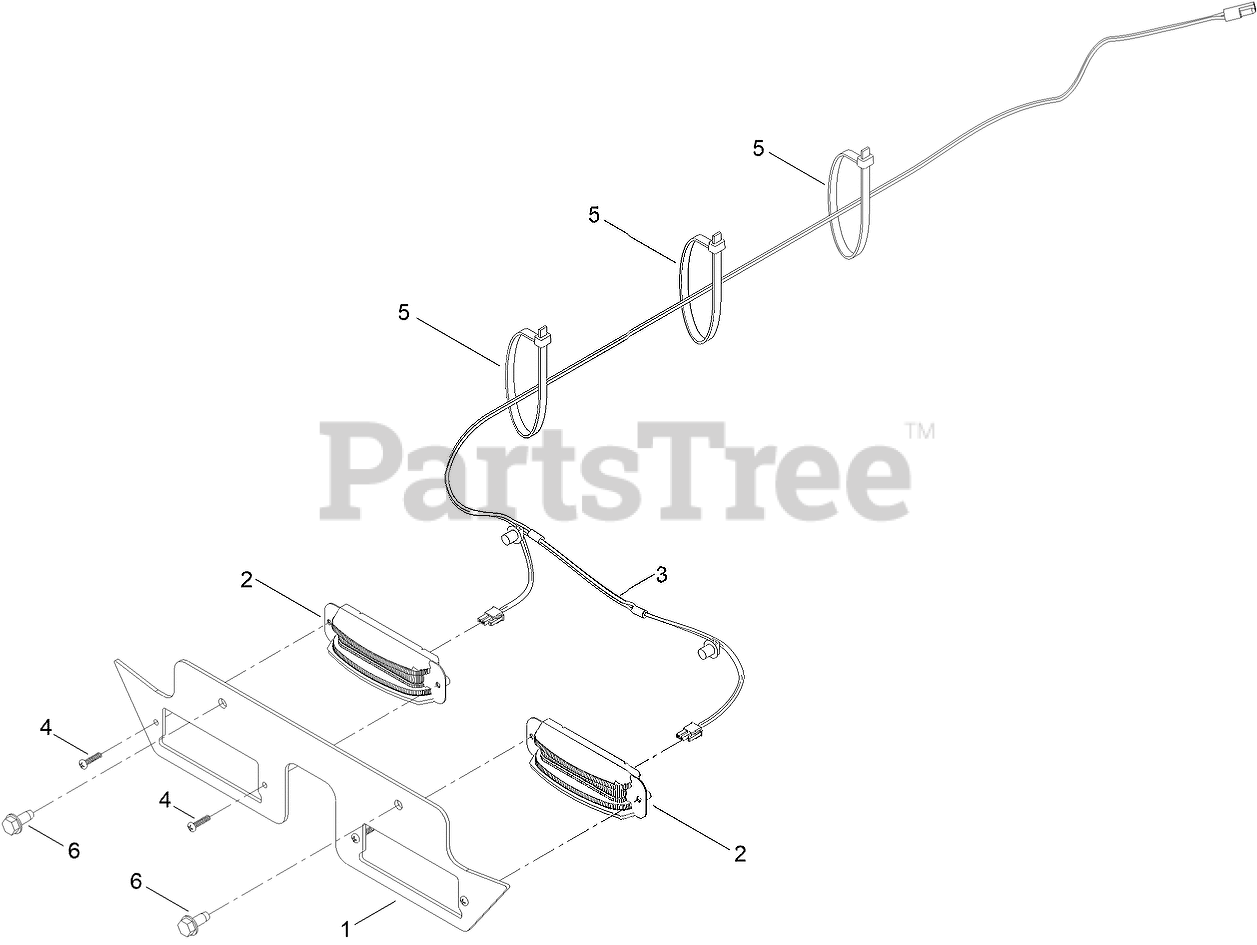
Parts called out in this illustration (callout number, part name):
1	MOUNT-HEAD LIGHTS
2	ASM-LIGHT,LED
3	HARNESS-WIRE, LED LIGHTS
4	SCREW-PPH
5	TIE-CABLE
6	SCREW-HWHTF
